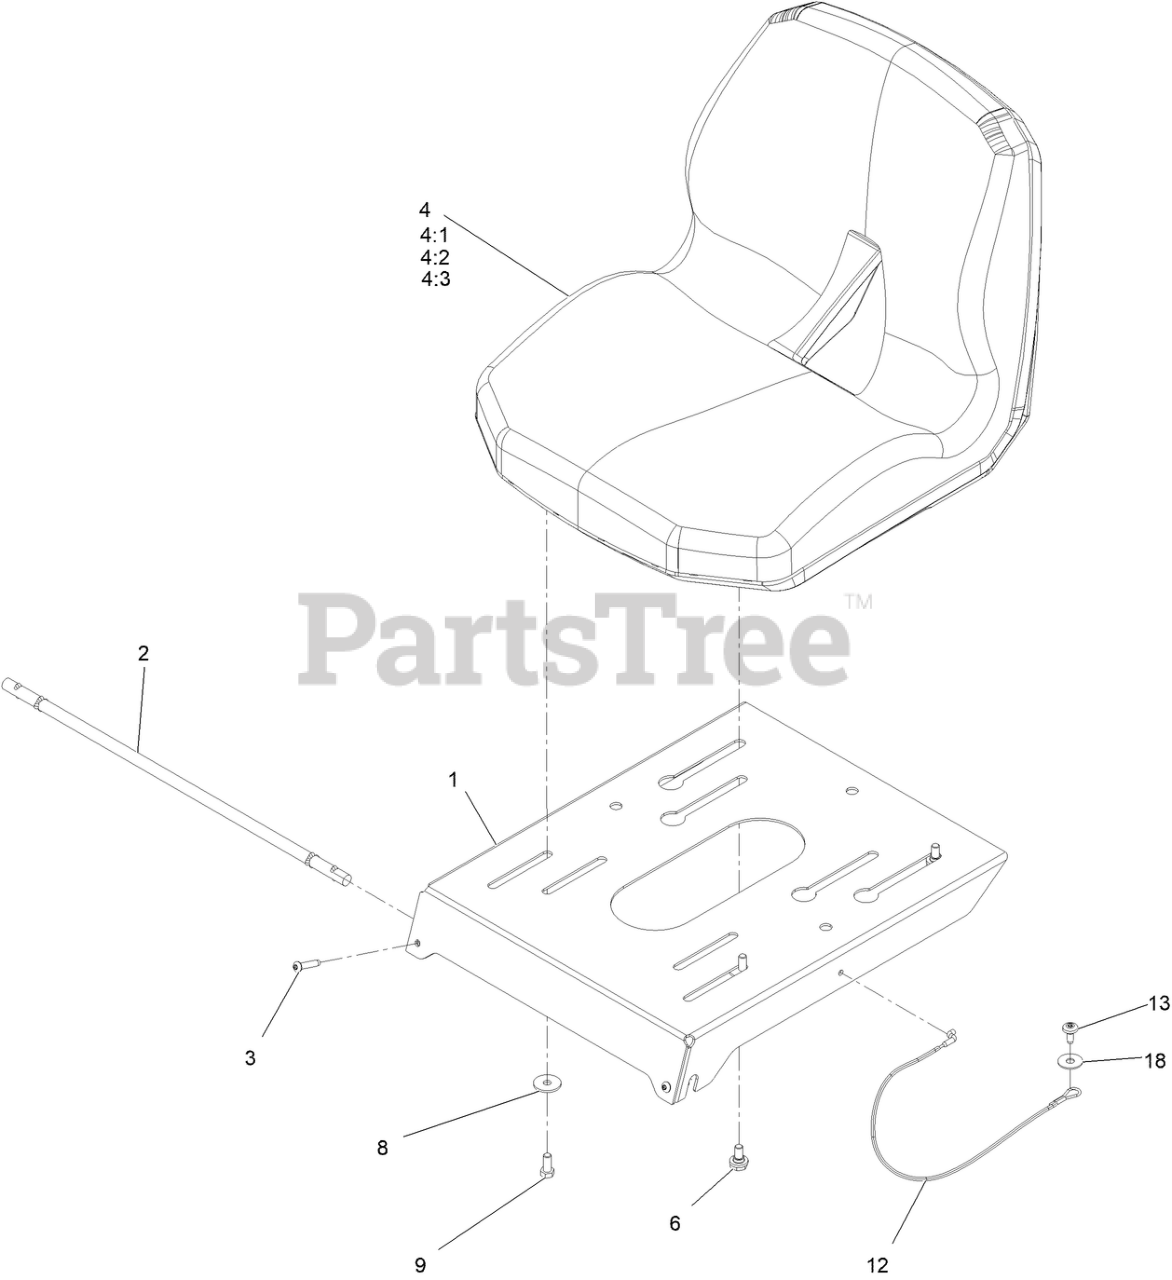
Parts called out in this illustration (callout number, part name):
2	ROD-PIVOT
3	SCREW-TTH, THREAD ROLLING
4	Seat-16 In
4:1	SEAT-16 IN
4:2	Cover-Seat
4:3	SWITCH-BAIL
6	BOLT-SHOULDER,HFH
8	WASHER-PIVOT
9	SCREW-HH
12	CABLE-LANYARD
13	SCREW-SHOULDER
18	Washer-Flat
